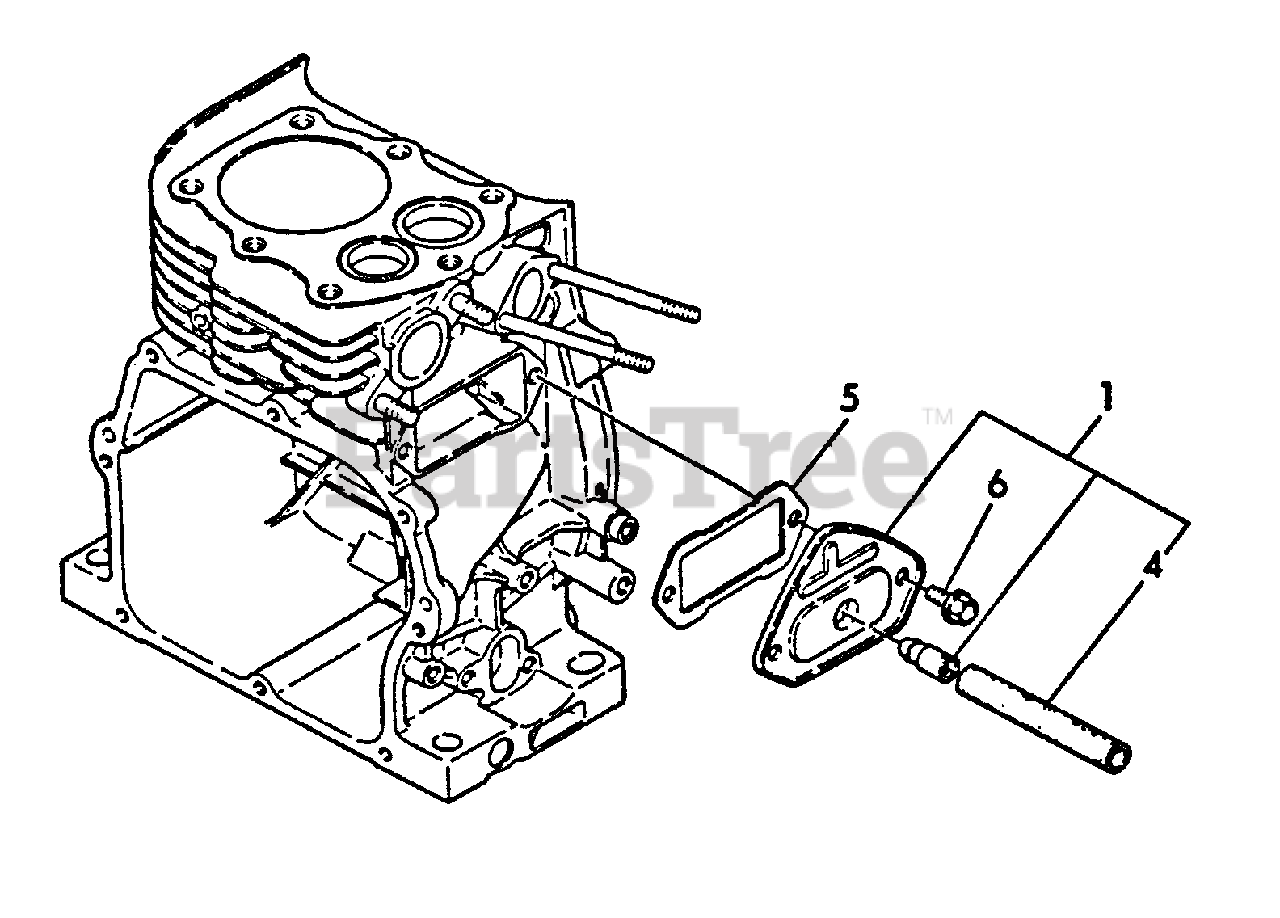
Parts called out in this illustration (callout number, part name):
1	VENT, FUEL TANK
4	PIPE - BREATHER
5	GASKET, BREATHER
6	BOLT - 6X8 -- PLATED
